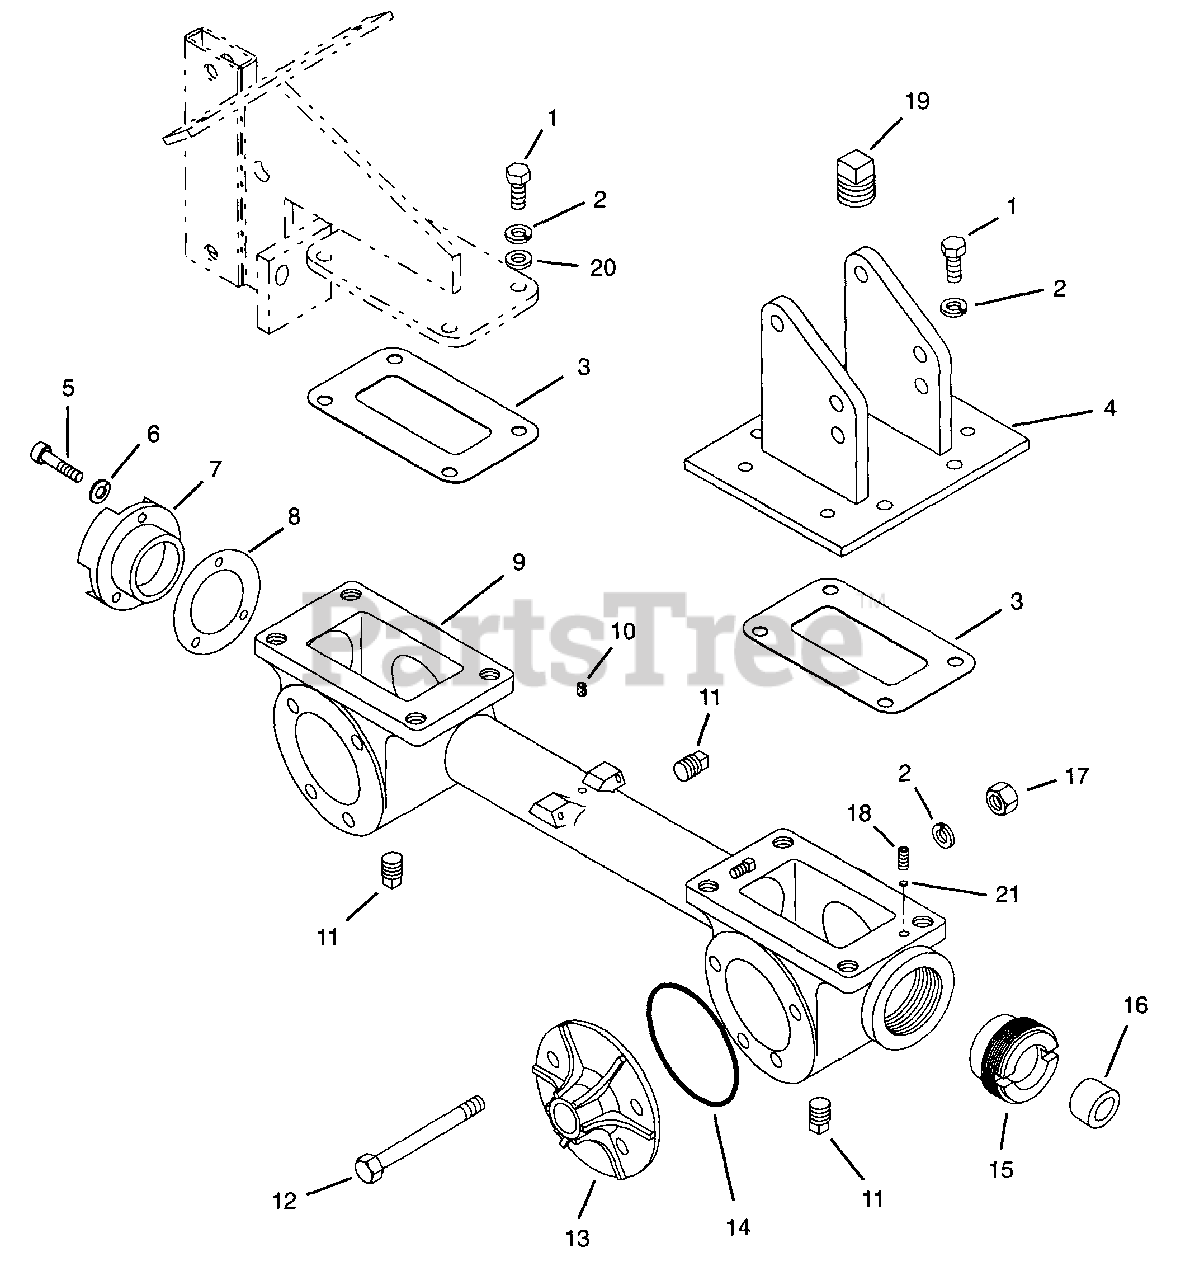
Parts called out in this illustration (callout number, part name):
1	@BLT-HEX .31-18X1.00 GR5 YWZC
2	@WSHR-LK .31X.078 REG YWZC
4	HANDLEBAR MOUNT
5	SCR-SKH .25-20X.75 PL
6	@WSHR-LK .25X.062 REG YWZC
7	REAR CAP
8	GASKET - REAR CAP
9	GEAR CASE
10	BREATHER
11	PIPE PLUG, 1/4 NPT
12	@BLT-HEX .31-18X3.50 GR5 YWZC
13	AXLE HOUSING
14	O-RING 3.625X3.875X.135
15	ADJUSTMENT PLUG
16	SEAL .750X1.250X.136
17	@NUT-HEX .31-18 YWZC
18	SCR-SET .25-20X.25 SKHCUPDL
19	PIPE PLUG
20	@WSHR-FL-STL.344X.688X.065YWZC
